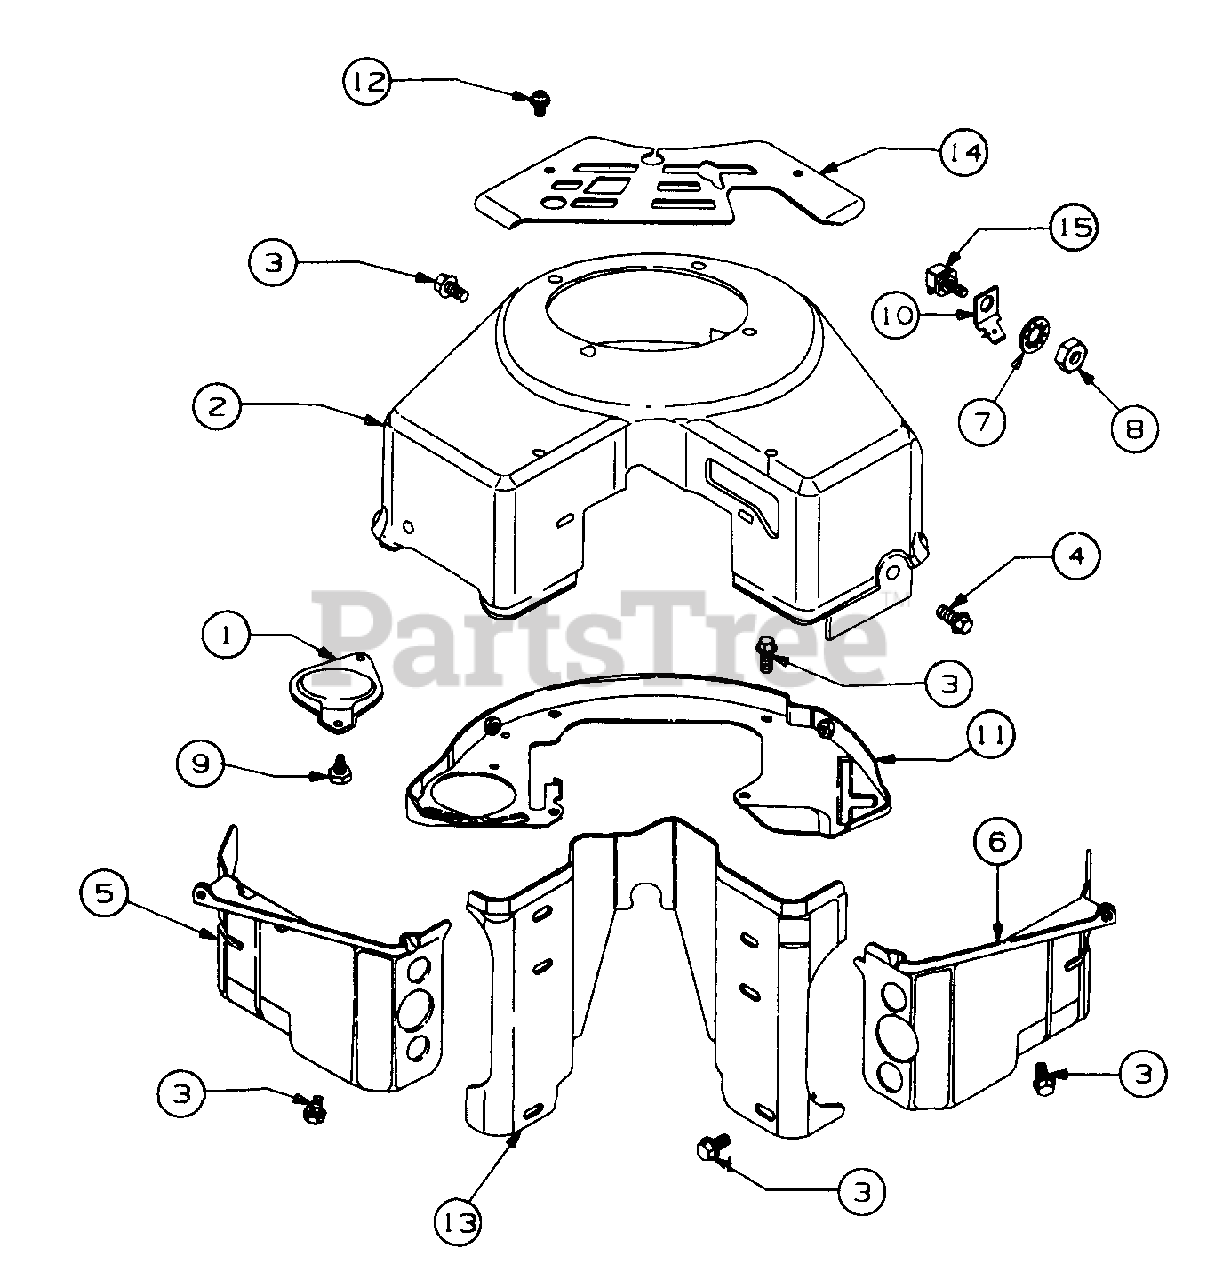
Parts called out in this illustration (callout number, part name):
1	Cover, Starter
2	Housing, Blower
3	Screw, Sem
4	Screw, Sem
5	Cover, Air Guide (Cylinder #1)
6	Cover, Air Guide (Cylinder #2)
7	Washer, Lock
9	Screw, Sem
10	Terminal, Spade
11	Back Plate Assy
12	Screw, Sem
13	Valley Cover, Air Guide
14	Cover, Carburetor
15	Insulator Assy
